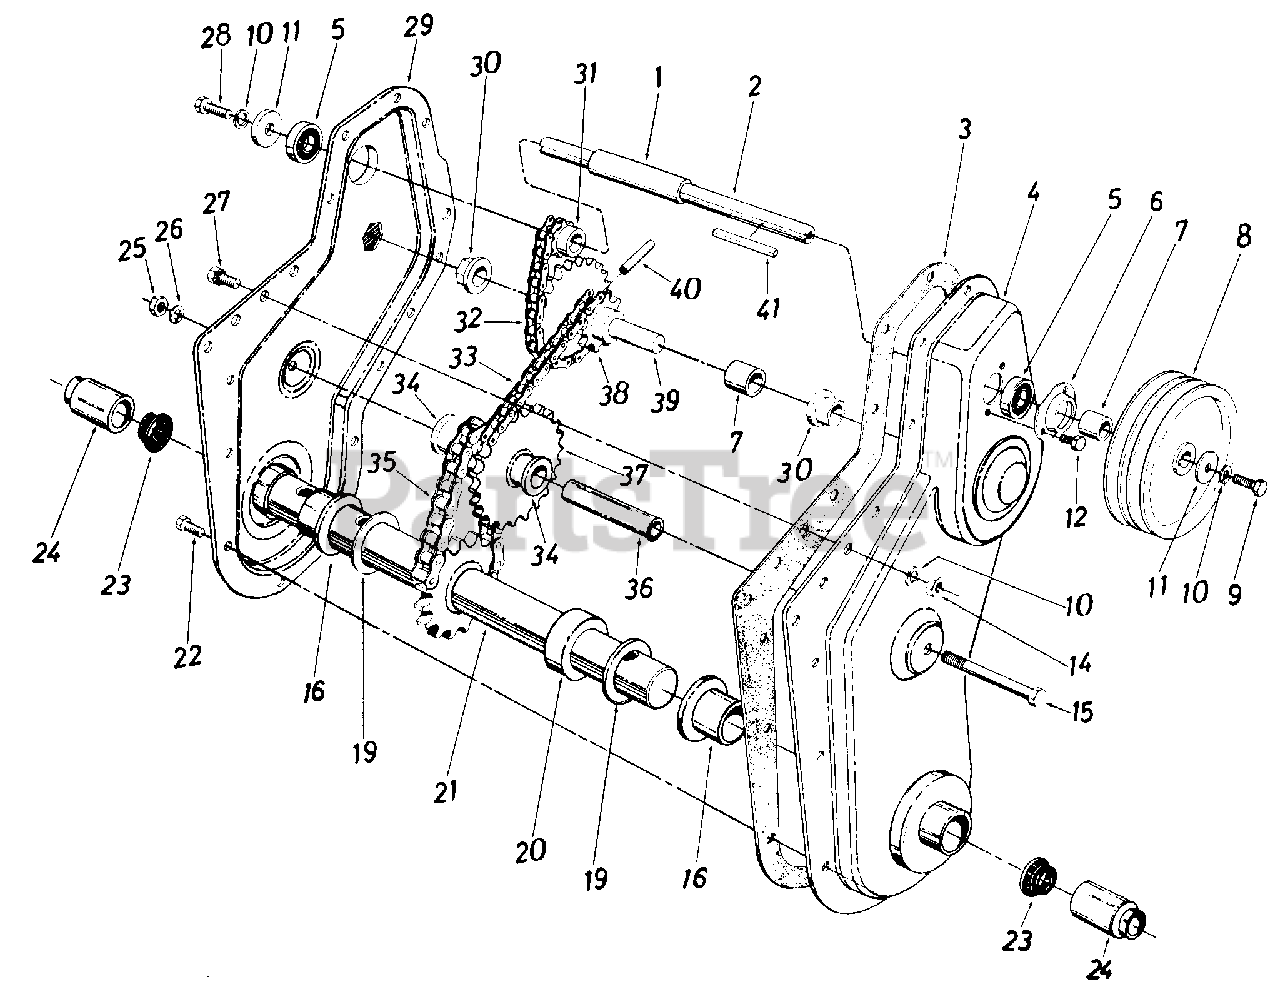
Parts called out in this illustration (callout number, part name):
1	Spacer .657 I.D. x .78 O.D. x 2.19" Lg.
2	Jackshaft
3	Housing Gasket
4	Housing Ass'y.-L.H. Half
5	Ball Bearing .625 I.D. x 1.375 O.D.
6	Bearing Housing
7	Spacer .635 I.D. x .88 O.D. x 1.03" Lg.
8	Chain Case Pulley 6.0" Dia.
9	Hex Bolt 5/16-18 x 1.0" Lg.
10	L-Wash. 5/16" I.D.*
11	Fl-Wash. .344" I.D. x 1.125" O.D.
12	Hex Wash. Hd. Self-Tap Scr. 1/4-20 x .50" Lg.
14	Hex Nut 5/16-18 Thd.
15	Hex Bolt 3/8-16 x 3.25" Lg.
16	Flange Bearinn (Plastic)
19	Flat Thrust Wash.
20	Step Spacer
21	Tine Shaft Ass'y.
22	Hex Wash. Hd. Self-Tap Scr. 1/4-20 x .50" Lg.
23	Seal Ring
24	Dust Cap
25	Hex Nut 3/8-16 Thd.
26	L-Wash. 3/8" I.D.
27	Hex Sems Bolt 5/16-18 x 1.00" Lg.
28	Hex Bolt 5/16-18 x .62" Lg.
29	Housing Ass'y.-R.H. Half
30	Hex Flanged Bearing
31	Sprocket 10 Teeth 1/2" Pitch
32	#41 Chain 1/2" Pitch x 34 Links
33	#420 Chain 1/2" Pitch x 48 Links
34	Flange Bearing .625" I.D.
35	#50 Chain 5/8" Pitch x 28 Links
36	Sprocket Shaft
37	Sprocket Bearing Sleeve Ass'y.
38	Sprocket Sleeve Ass'y.
39	Sprocket Shaft
40	Spring Pin Spiral 1/4" Dia. x 1.5" Lg.
41	Square Key 3/16 x 3/16 x 1.50" Lg .
